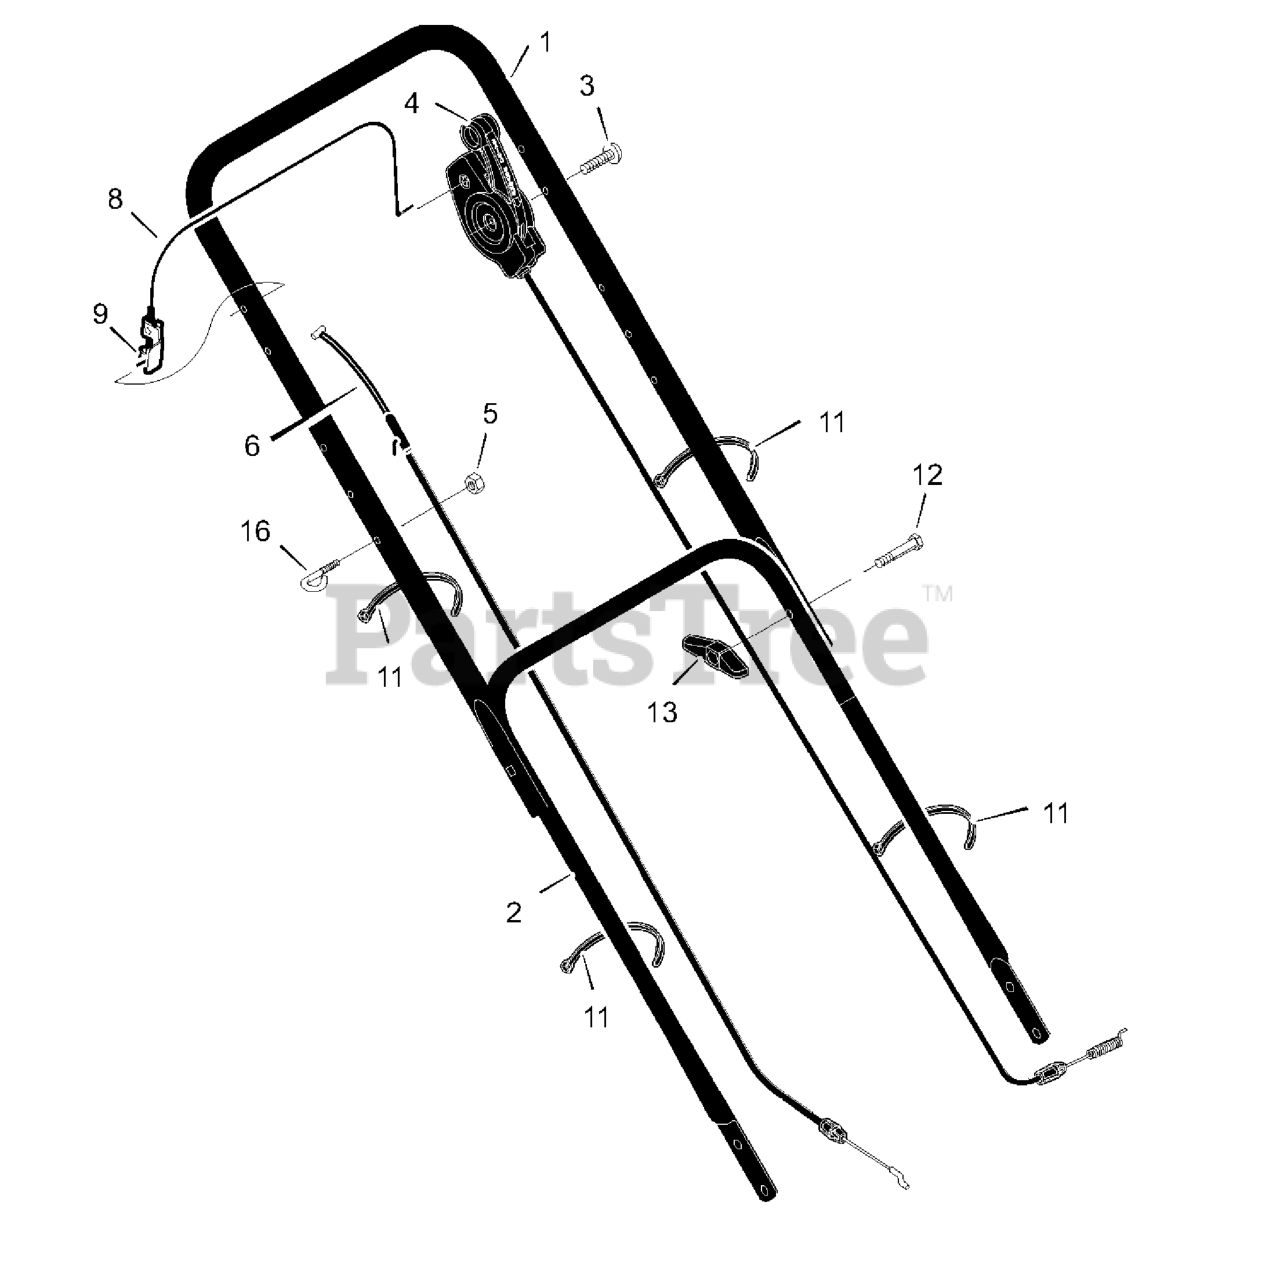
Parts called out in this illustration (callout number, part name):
1	Handle, Upper (Black)
2	Handle, Lower (Black)
4	Control, Drive
5	Locknut
6	Cable, Stop
8	Lever, Stop
9	Bracket, Stop Lever
11	Fastener, Cable
13	Knob
16	Guide, Rope
